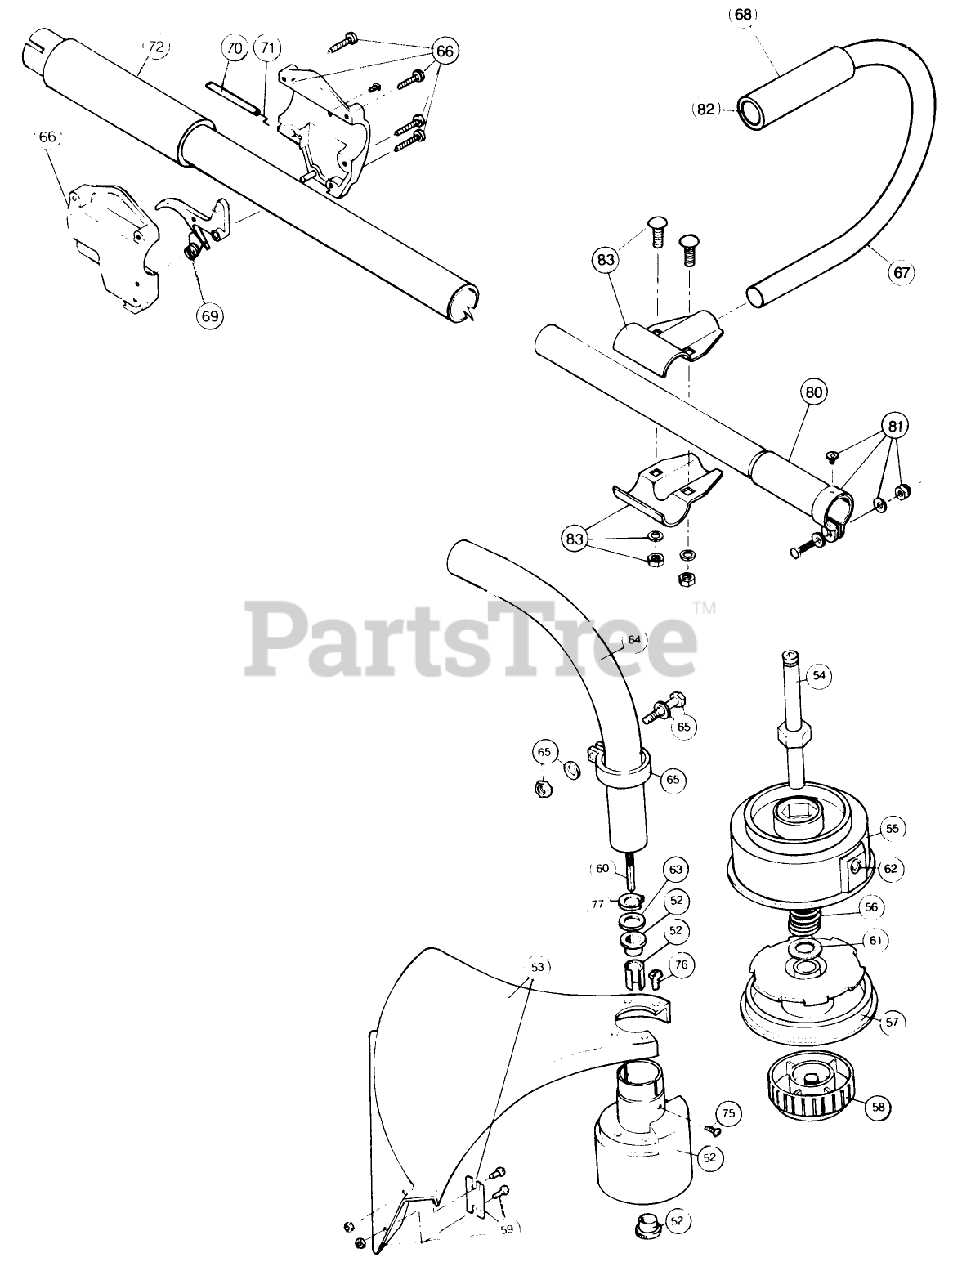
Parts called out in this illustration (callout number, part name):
52	BUSHING HSG ASM
56	SPRING
57	REEL - INNER
59	BLADE ASM
61	RETAINER WASHER
62	EYELET
63	WASHER
66	THROTTLE TRIGGER ASM
68	HANDLE NITRILE GRIP
69	THROTTLE TRIGGER SPRING
70	THROTTLE CABLE HSG
71	THROTTLE CABLE WIRE
73	LOOP LINE
74	Tie Strap
75	ANTI-ROTATION SCREW
76	GUARD MOUNTING SCREW
77	RETAINING RING
82	TUBE CLOSURE
